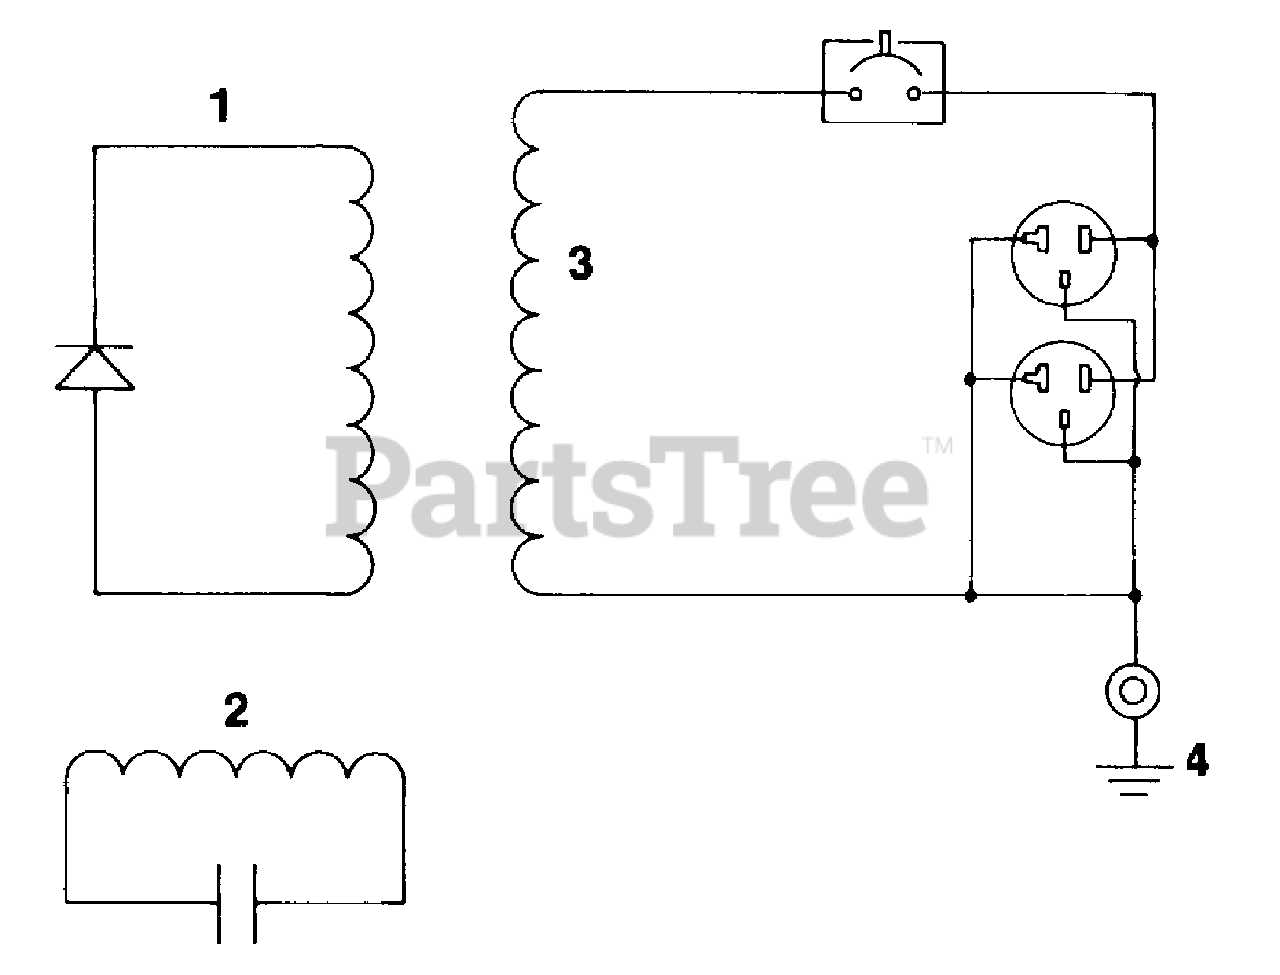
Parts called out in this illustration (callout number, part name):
1	Field Coil
2	Condenser, Coil
3	Main Coil
4	Ground
